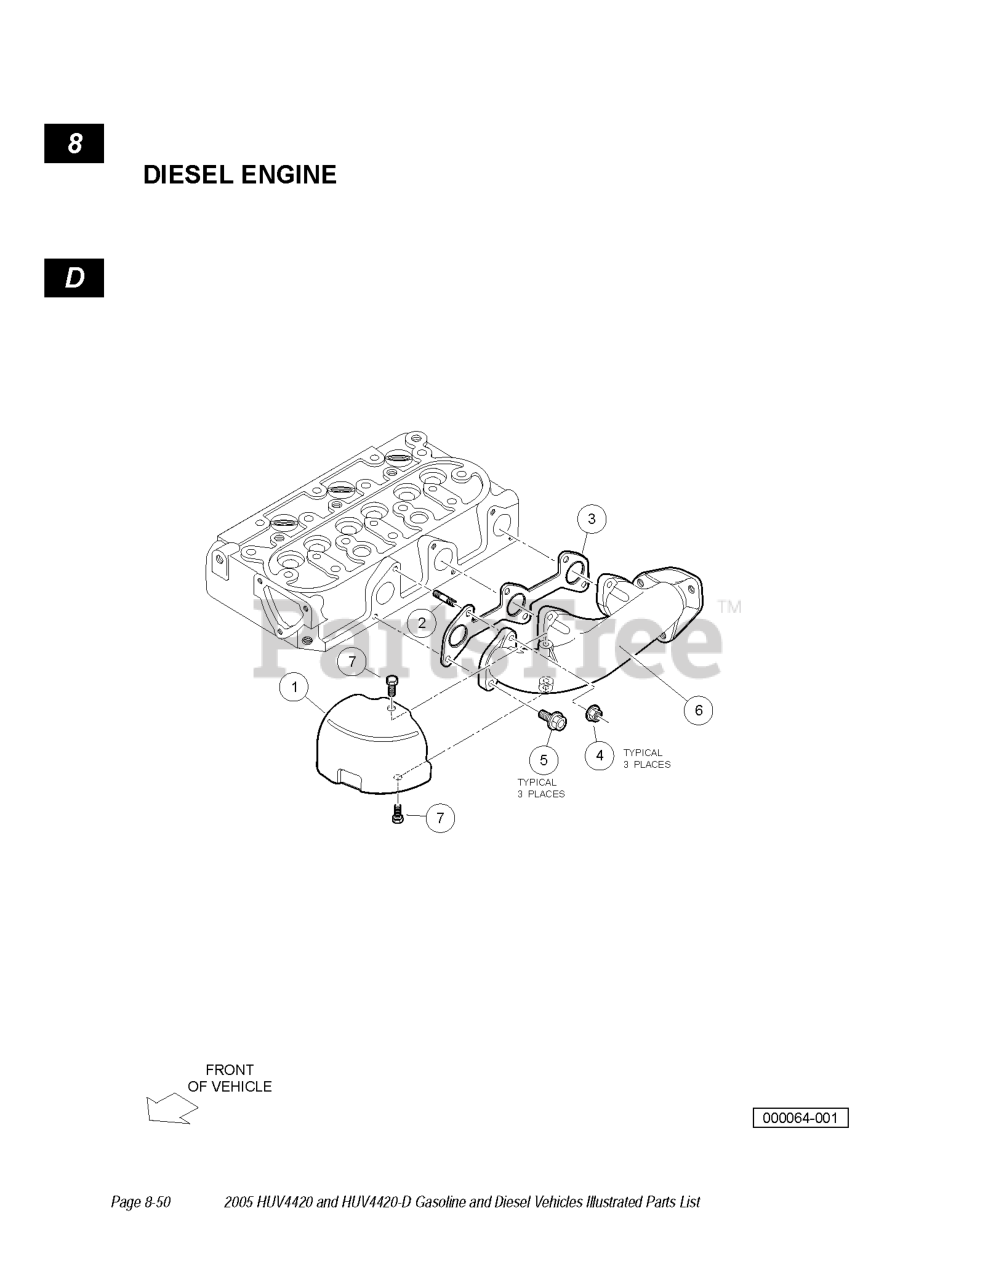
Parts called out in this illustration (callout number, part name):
1	Cover, Heat Proof
2	Stud, M6 X 26
3	GASKET, EX-MANIFOLD
4	Nut, Flange, M6, Ubs
5	Bolt, Flange Head, M6 X 1 X 16
6	MANIFOLD, EXHAUST, D722
7	BOLT, D722, EXHST MANFLD COVER
